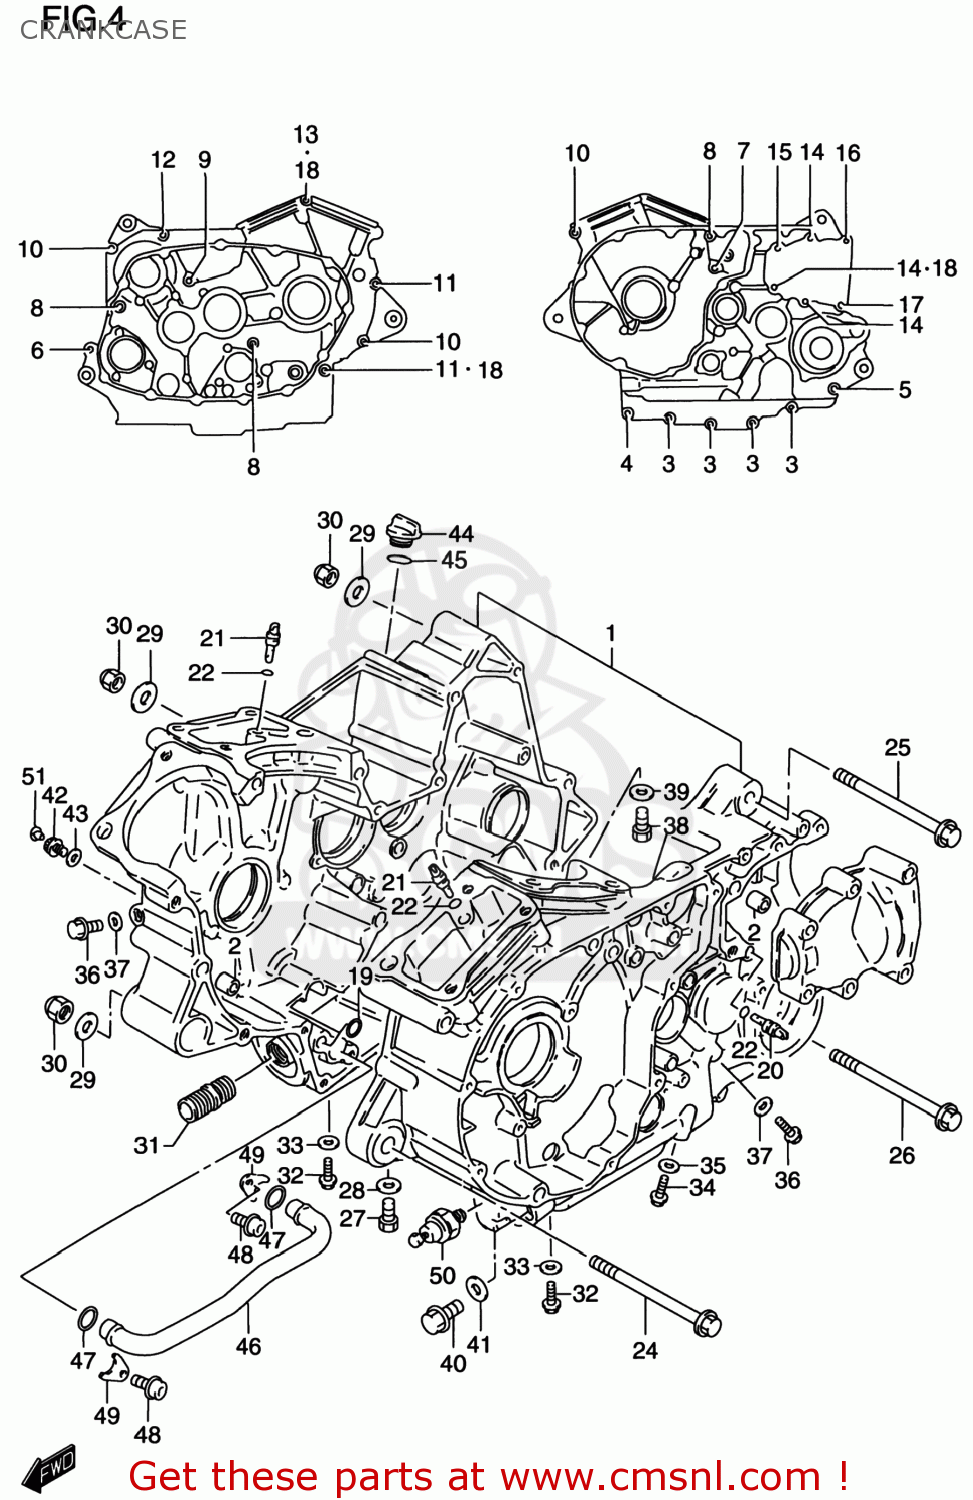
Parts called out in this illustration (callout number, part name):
1	CRANKCASE SET
2	PIN(8.4X11X20)
3	BOLT
4	BOLT
5	BOLT
6	BOLT
7	BOLT
8	BOLT
9	BOLT(8X120)
10	BOLT(8X95)
11	BOLT(8X105)
12	BOLT(8X120)
13	BOLT(8X160)
14	BOLT
15	BOLT
16	BOLT(8X55)
17	BOLT(8X65)
18	GASKET 8.2X14X1 (NAS)
19	O RING(D:1.9,ID:12.6)
20	JET,OIL GALLERY
21	JET,AIR(14)
22	O RING(D:1.2,ID:4)
23	WASHER(48.1X64X1.94)
24	BOLT(10X125)
25	BOLT(10X130)
26	BOLT(10X150)
27	BOLT
28	GASKET(12.1X16.2X3.7) (NAS)
29	WASHER
30	NUT
31	UNION,OIL STAND
32	BOLT
33	GASKET 8.2X14X1 (NAS)
34	PLUG(10X12)
35	GASKET(10X14X3.6) (NAS)
36	BOLT
37	GASKET(5.8X11X1.2) (NAS)
38	PLUG
39	GASKET(16X22X2) (NAS)
40	PLUG(14X12)
41	GASKET(13.8X18.8X4.8) (NAS)
42	BOLT
43	GASKET 8.2X14X1 (NAS)
44	PLUG
45	O RING(D:3.1,ID:16.8)
46	PIPE,OIL GALLERY
47	O RING(D:3.1,ID:14.8)
48	BOLT
49	CLAMP,OIL PIPE
50	SWITCH ASSEMBLY,OIL PRESSURE
51	CAP(OD:11)
